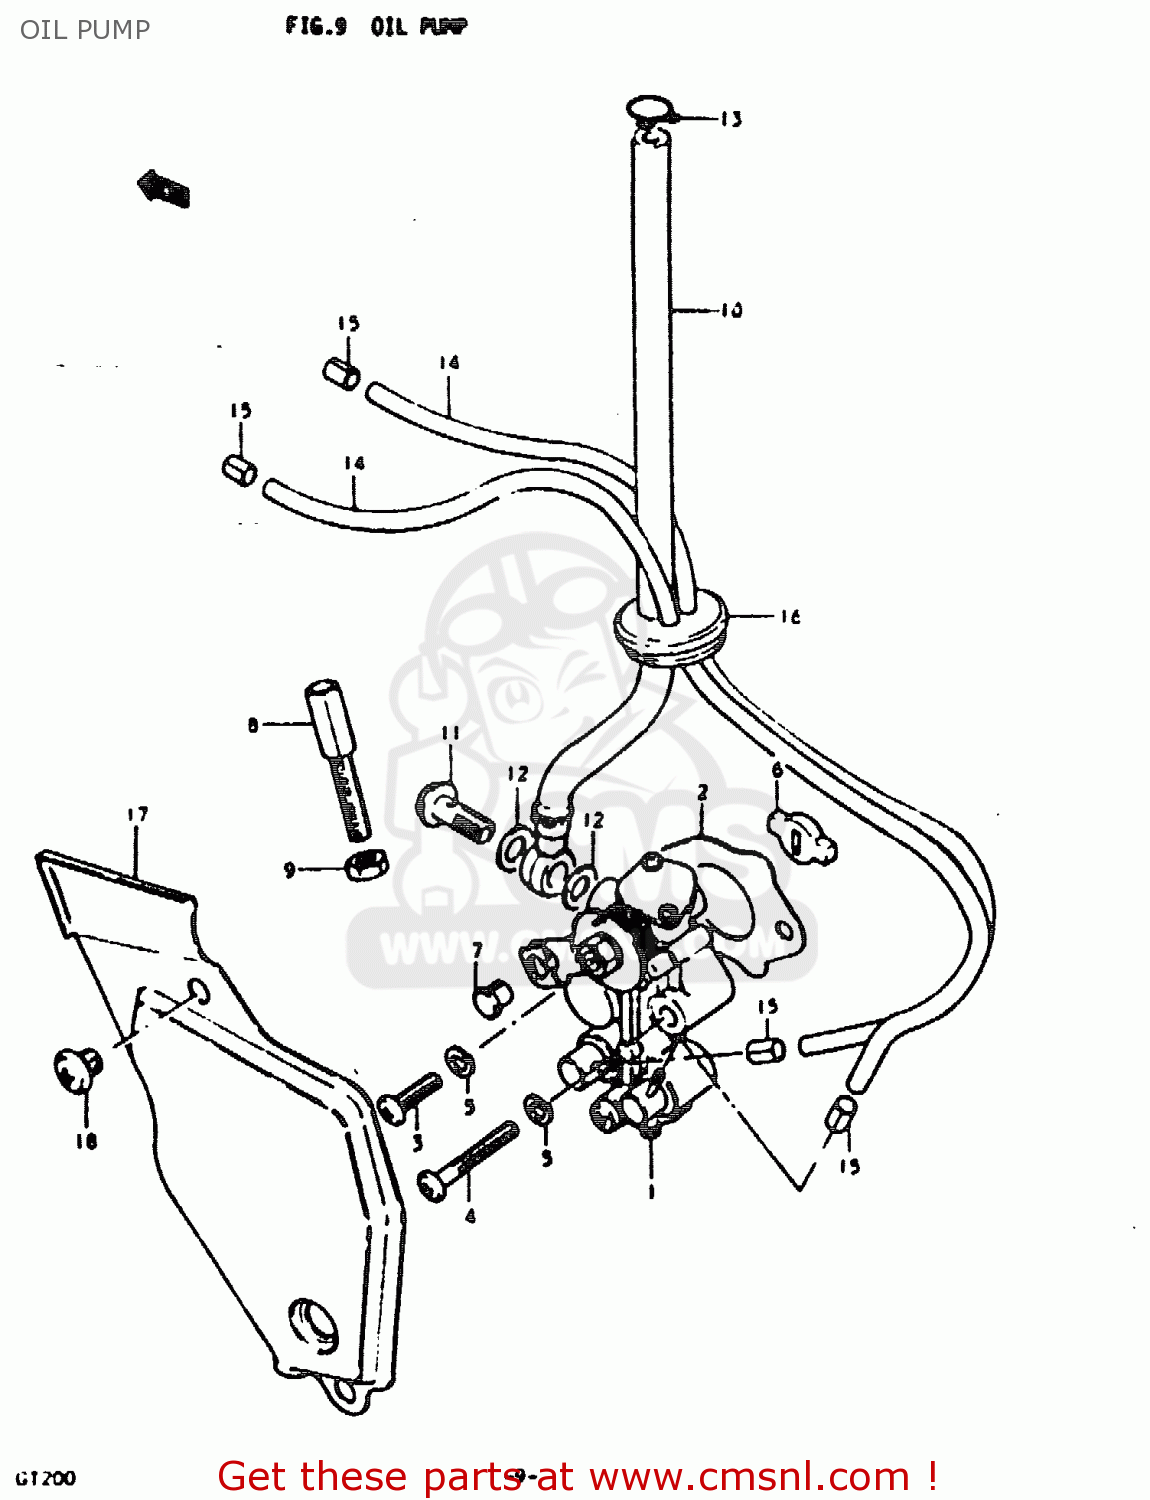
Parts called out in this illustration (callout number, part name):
1	PUMP ASSY, OIL
2	GASKET,OIL PUMP (NAS)
3	SCREW
4	SCREW
5	LOCK WASHER
6	PIECE,OIL PUMP DRIVE
7	TERMINAL,CABLE
8	BOLT
9	NUT
10	HOSE,OIL NO.1
11	UNION BOLT
12	GASKET(6.2X11X1).2 (NAS)
13	CLIP
14	HOSE, OIL NO.2
15	CLIP
16	GROMMET,OIL HOSE
17	CAP, INSPECTION
18	SCREW
